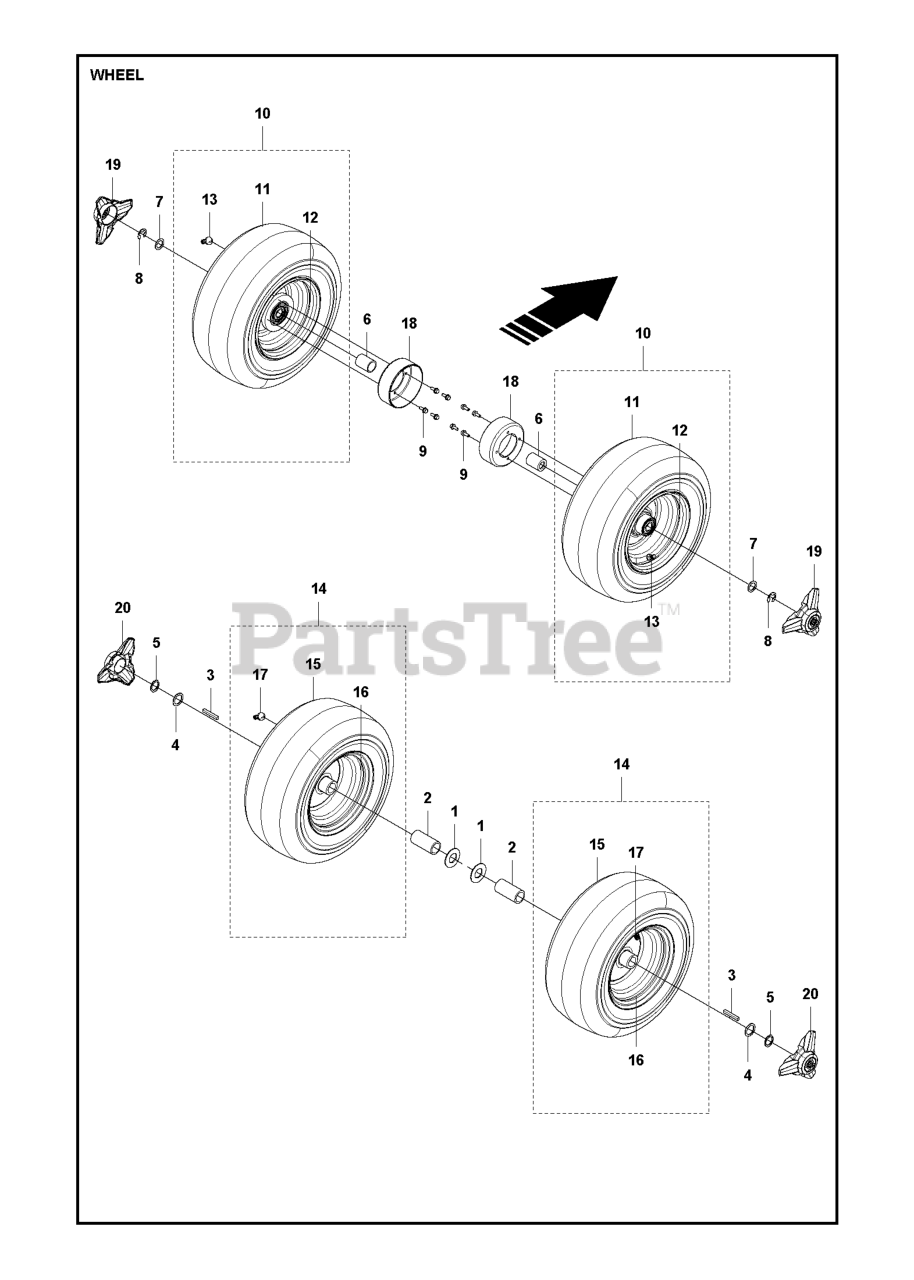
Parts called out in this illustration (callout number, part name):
8	RETAINING RING
9	SCREW
13	VALVE
17	VALVE
